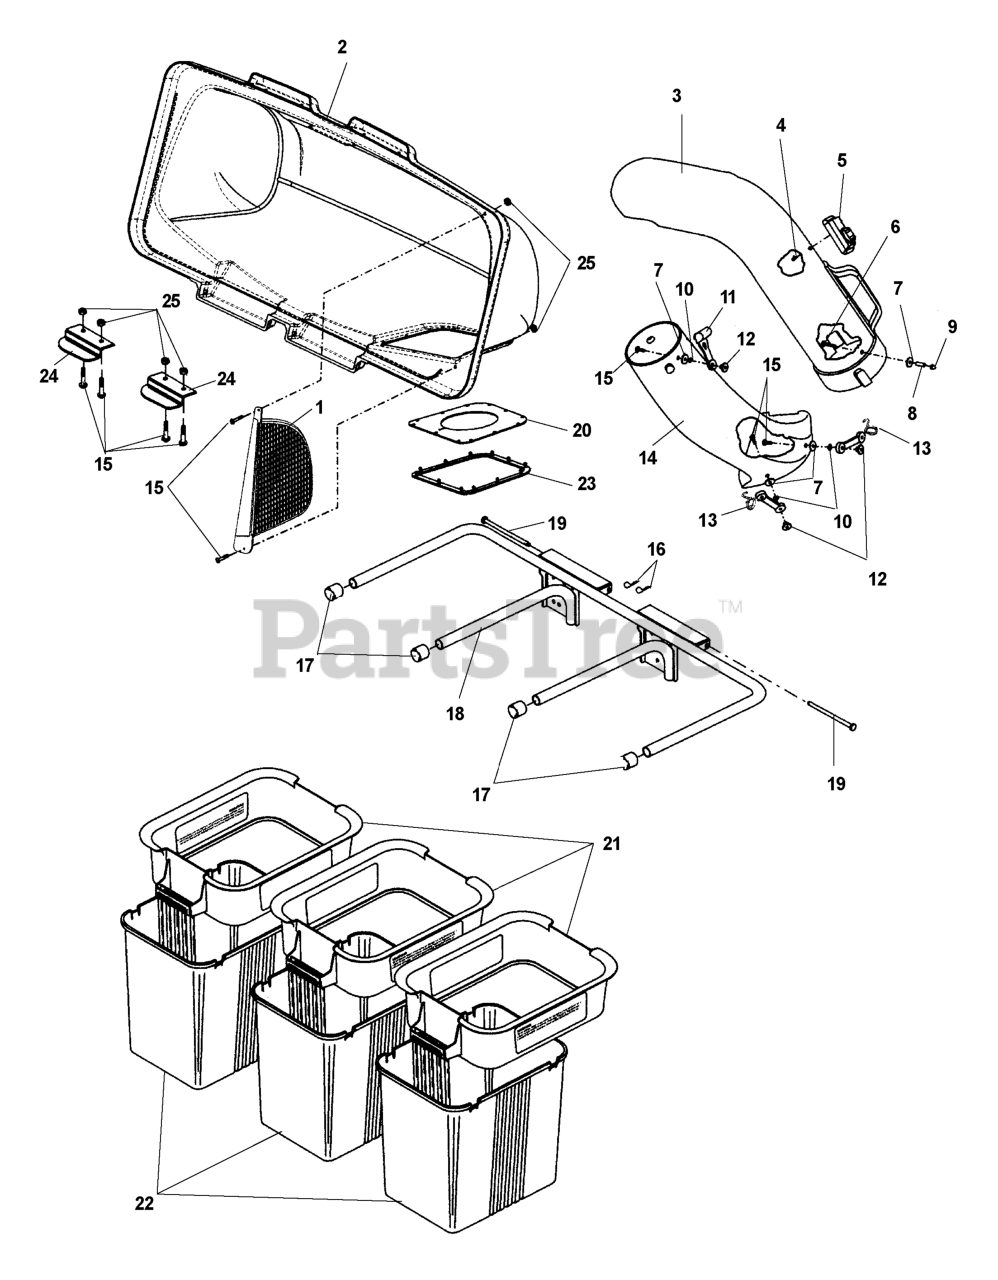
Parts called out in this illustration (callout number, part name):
1	SCREEN.COVER.BAGGER
2	COVER.ASM.3BIN.GENERIC.
3	CHUTE.COLLECTION.UPPER
4	SCREW
5	DUMP BAG INDICATOR
6	SCREW #10-24 X 1-1/8 ZD SPEC
8	BSHG .202X.75 LG SPLIT ZD SPEC
9	NUT 10-24 ACORN ZD
10	WASHER - 3/16 LOCK ZD
11	HOOD LATCH
12	NUT 10-24 WELD PLATED
13	LATCH ASSY TBR
14	LOWER CHUTE
14	CHUTE, LOWER 54
15	SCREW #10-24 X 5/8
16	RETAINER SPRING
17	TUBING PLUG
18	BAGGER, FRAME
19	BAGGER.HINGE.PIN
20	SEAL.BAGGER.TOP.3-BIN.BLK
21	CONTAINER TOP
22	CONTAINER BOTTOM
23	GASKET.COVER.BAGGER
24	LATCH CER38
25	NUT 10-24 NYLOC
